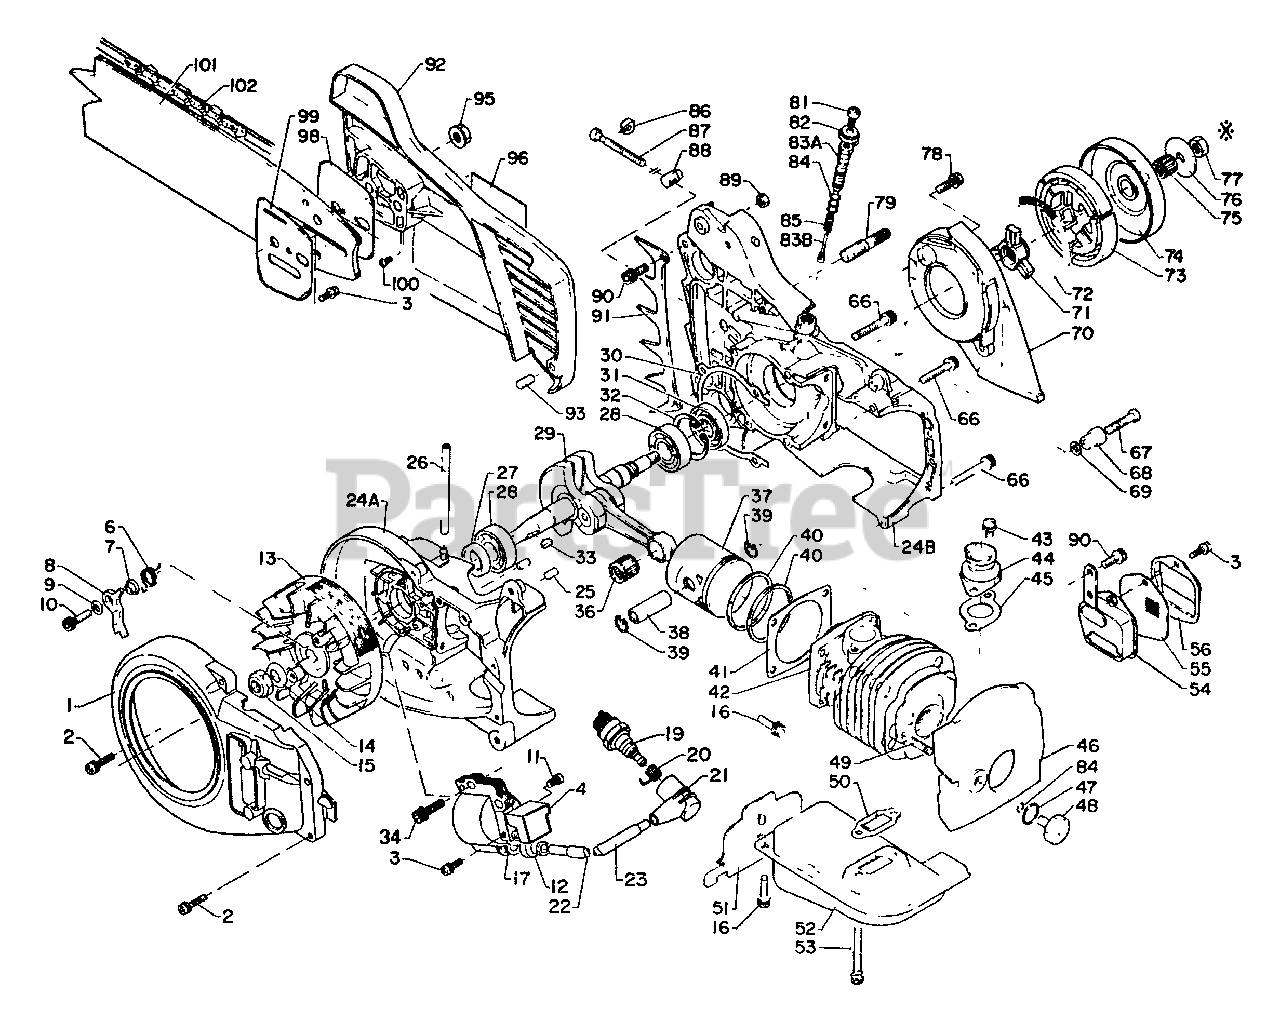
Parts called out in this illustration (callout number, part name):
1	SHIELD, FAN
2	SCREW - 4X20
3	SCREW - 4X12
4	COIL, IGNITION
6	SPRING, RETURN
7	SPACER
8	PAWL, STARTER
9	WASHER - 5
10	SCREW - 5X20
11	SCREW - 4X6
13	FLYWHEEL
14	LOCKWASHER
16	SCREW - 5X20
17	COIL, IGNITION
19	SPARK PLUG -- BPM-7A
20	TERMINAL, SPARK PLUG CAP
21	CAP, SPARK PLUG
22	LEAD, SPARK PLUG
24	CRANKCASE KIT
24A	CRANKCASE KIT
24B	CRANKCASE KIT
25	PIN - LOCATING
26	PIPE - 3X6X75 -- BLACK
27	SEAL, OIL
28	BEARING, BALL - 6202
29	CRANKSHAFT ASSY
30	GASKET, CRANKCASE
31	SEAL, OIL
32	RING, RETAINING - 35
34	SCREW - 5X20
36	BEARING, NEEDLE
37	PISTON
38	PIN, PISTON
39	RING, RETAINING
40	RING, PISTON
41	GASKET, CYLINDER
42	CYLINDER
43	SCREW - 5X10
44	ADAPTOR, INTAKE
45	GASKET, INTAKE
46	COVER, CYLINDER
47	O-RING - 12
48	NUT
50	GASKET, EXHAUST
51	INSULATOR
52	MUFFLER
53	SCREW - 5X40
54	ADAPTOR
55	SCREEN, SPARK ARRESTOR
56	GUIDE, EXHAUST
66	SCREW - 5X35
67	SCREW - 5X25
68	CHAIN CATCHER KIT
69	WASHER - 5
70	SEAL, DUST
71	HUB, CLUTCH
72	SPRING, CLUTCH
73	SHOE, CLUTCH
74	DRUM, CLUTCH
75	BEARING, NEEDLE
76	WASHER, CLUTCH
77	LOCKNUT
78	SCREW - 5X16
79	STUD, GUIDE BAR
81	SCREW - 5X10
82	LOCKWASHER
83	AUTO-OILER ASSY
83A	AUTO-OILER ASSY
83B	AUTO-OILER ASSY
84	O-RING - 5
87	SCREW, TENSIONER
88	TENSIONER, CHAIN
89	LOCKNUT - 5
90	SCREW - 5X12
91	SPIKE
92	GUARD, SPROCKET
93	PIN - LOCATING
95	NUT - FLANGE
96	LABEL - ECHO
98	PLATE, GUIDE - OUTER
99	PLATE, GUIDE - INNER
100	SCREW - 3X6
101	GUIDE BAR
102	CHAIN, SAW
